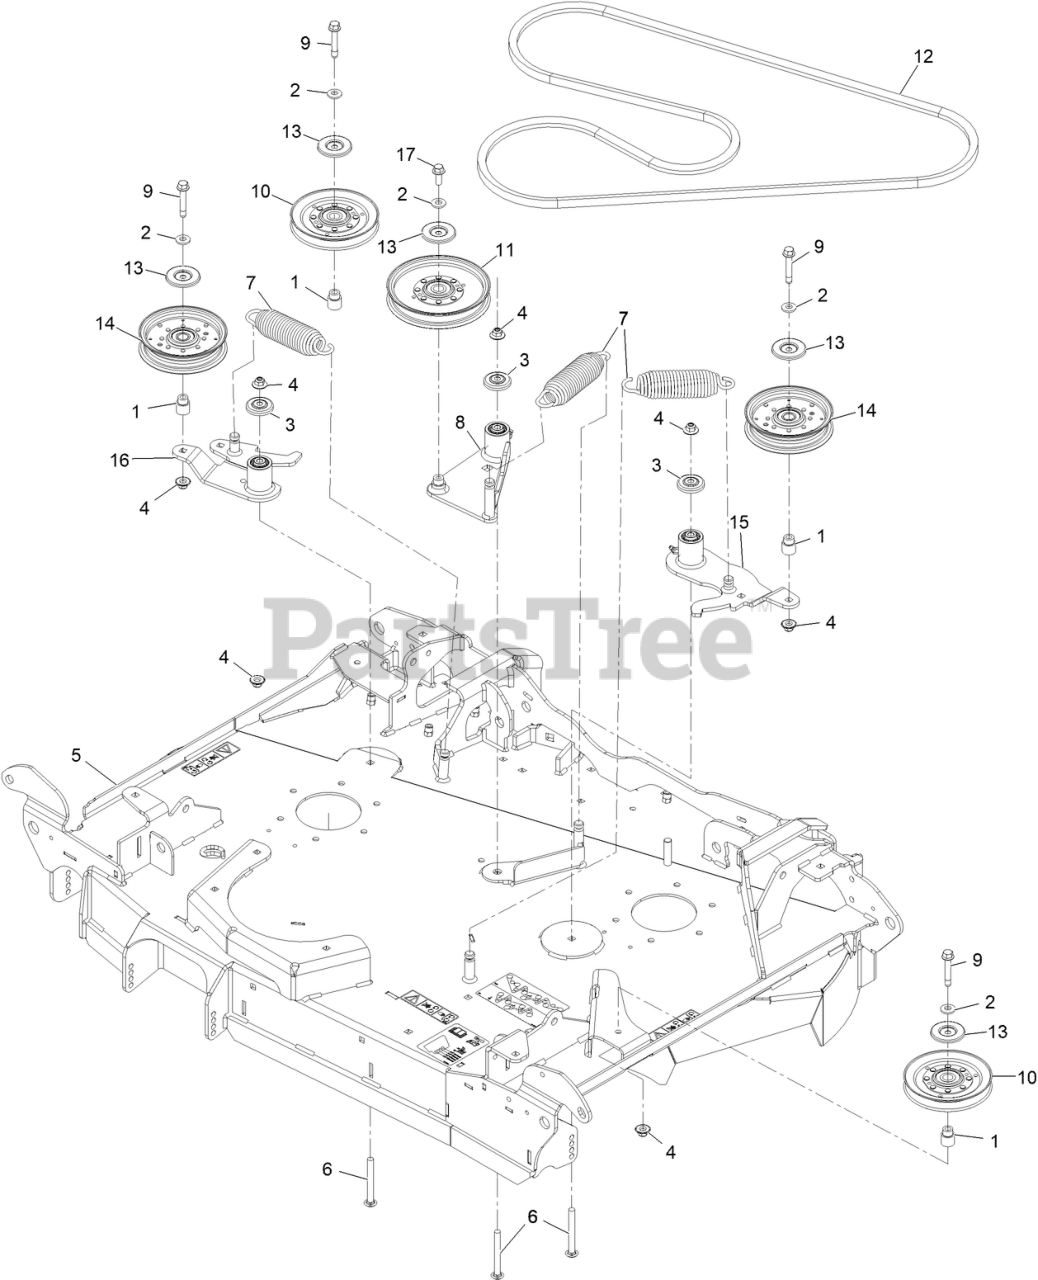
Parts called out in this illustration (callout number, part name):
1	BUSHING-IDLER
2	WASHER-BELLEVILLE
3	GUARD-TOP
4	Nut-Nyloc 3/8-16 Flg
5	ASM-Deck, Ctr 96/144
6	BOLT-SHOULDER, CARRIAGE 3/8-16 X 3 1/2
7	SPRING-EXTENSION
8	IDLER ARM ASM
9	SCREW-HHF
10	IDLER-V
11	IDLER-PULLEY
13	SHIELD-DUST
14	PULLEY-IDLER, FLAT
15	IDLER ASM
16	IDLER ASM
17	SCREW-HHF 3/8-16 X 1
